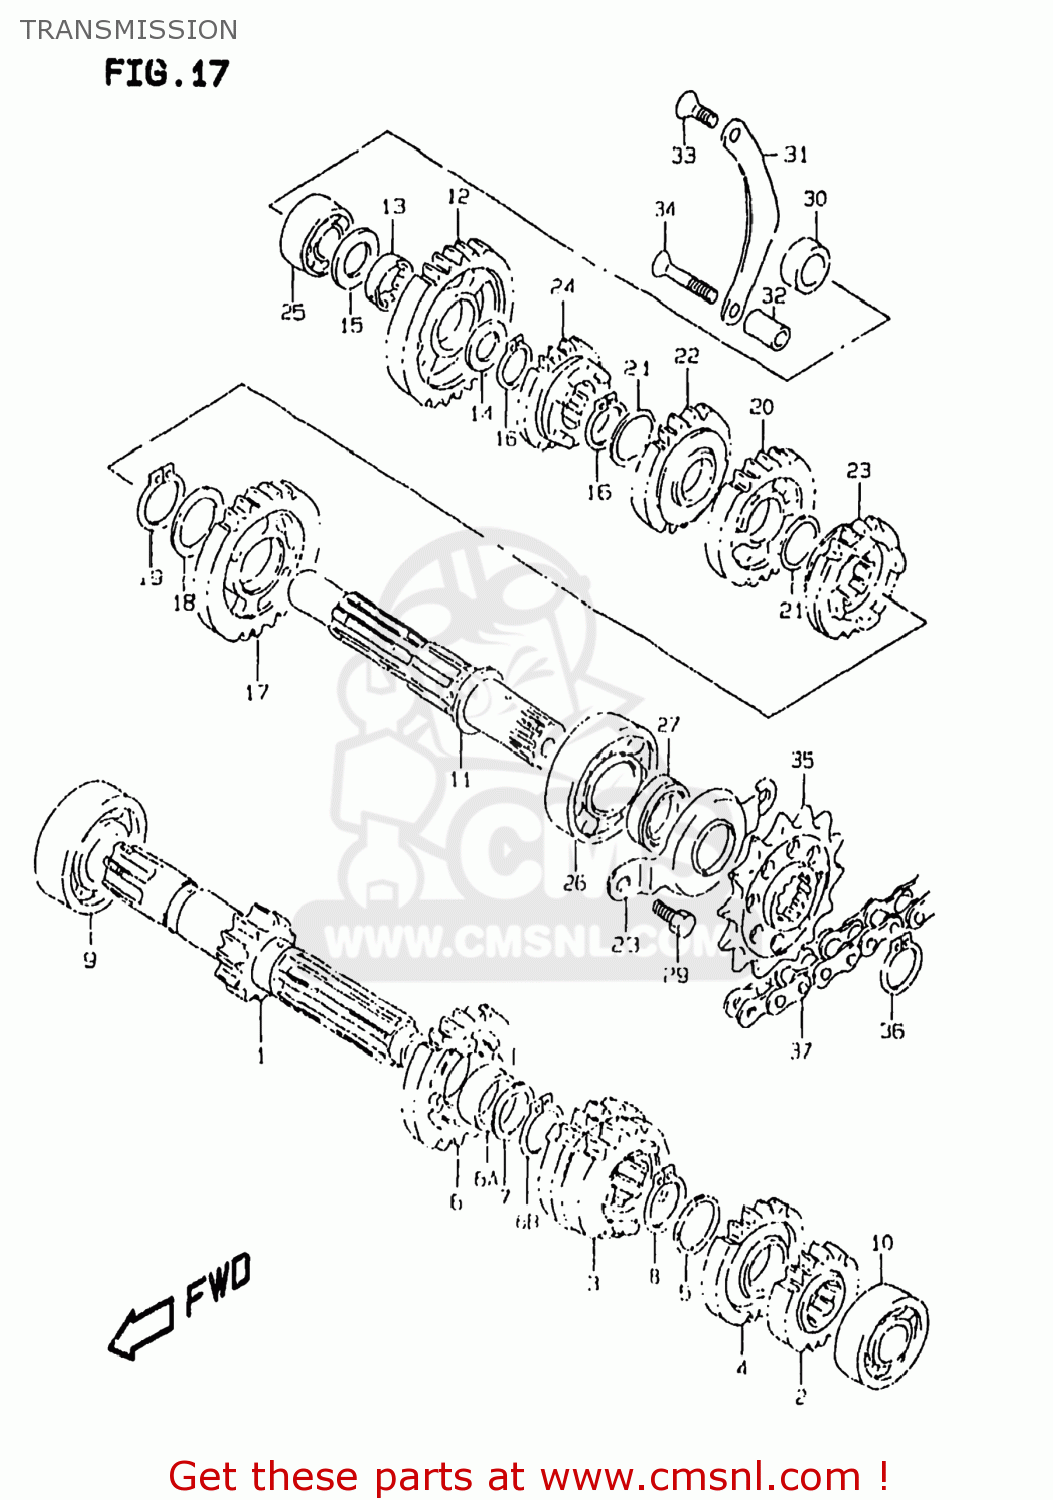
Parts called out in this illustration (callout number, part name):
1	SHAFT,COUNTER(NT:12)
2	GEAR,2ND DRIVE
3	GEAR,3RD & 4TH DRIVE(NT:18/18)
4	GEAR,5TH DRIVE(NT:21)
5	SHIM(22X26X1)
6	GEAR,6TH DRIVE(NT:23)
6A	BUSH(22X26X9)
6B	CIRCLIP
7	SHIM(22X30X1)
8	CIRCLIP
9	BEARING 20X52X15
10	BEARING
11	SHAFT,DRIVE
12	GEAR,1ST DRIVEN(NT:30)
13	BUSH,1ST DRIVEN GEAR
14	WASHER
15	SHIM(22X30X1)
16	CIRCLIP
17	GEAR,2ND DRIVEN(NT:26)
18	SHIM(25X34X1)
19	CIRCLIP
20	GEAR,3RD DRIVEN(NT:24)
21	SHIM(22X28X1)
22	GEAR,4TH DRIVEN(NT:20)
23	GEAR,5TH DRIVEN(NT:20)
24	GEAR,6TH DRIVEN(NT:19)
25	BEARING(17X40X17.5)
26	BEARING(22X56X16)
27	SEAL,OIL(22X34X7)
28	RETAINER,DRIVE SHAFT OIL SEAL
29	BOLT
30	SPACER(17X25X10.5)
31	RETAINER,KICK IDLE GEAR
32	SPACER(6.5X12X21)
33	SCREW ,6X16
34	SCREW
35	SPROCKET(NT:15)
36	CIRCLIP
37	CHAIN(DID520VM,108LE)
